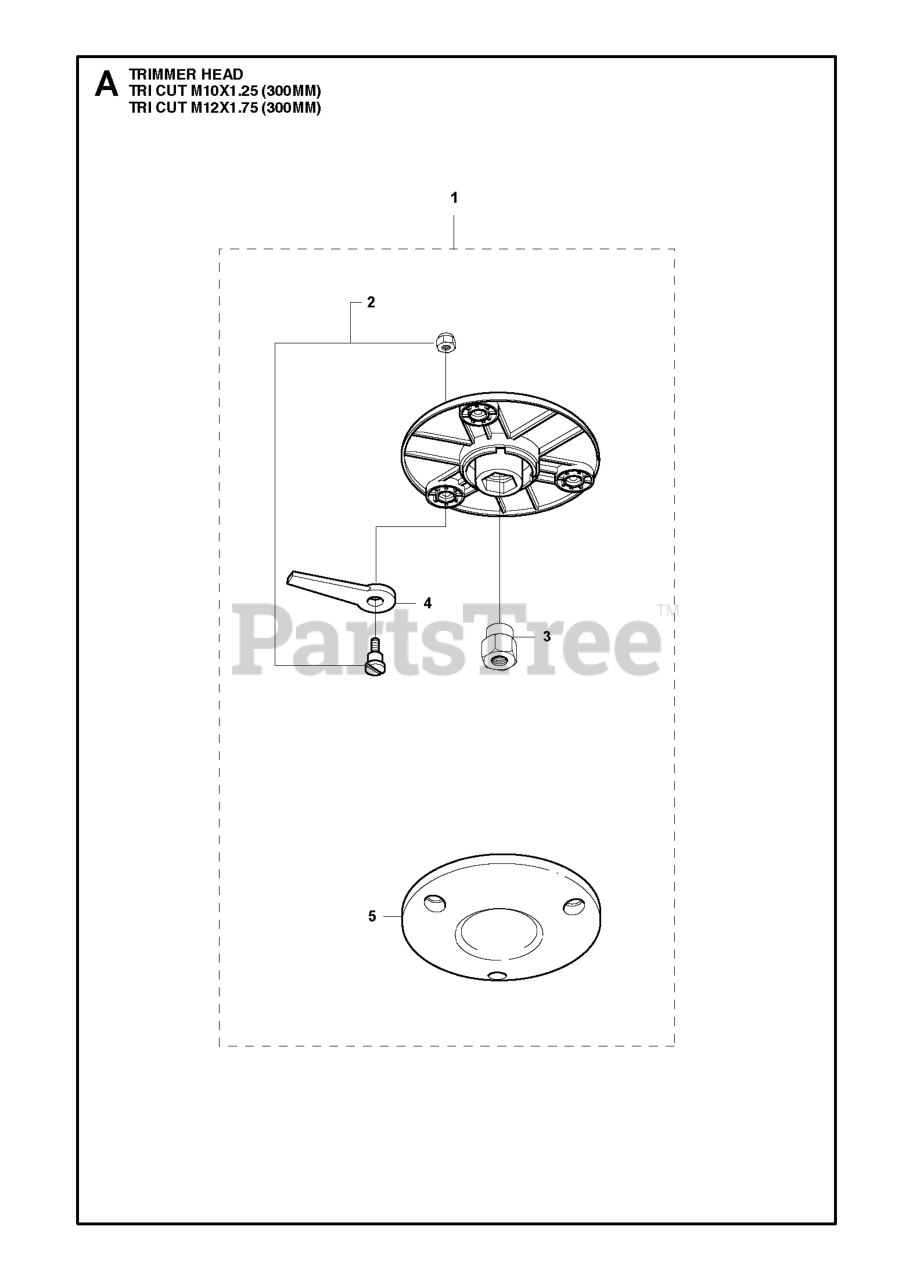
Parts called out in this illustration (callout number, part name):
2	SCREW/NUT/WASHER KIT
3	ADAPTOR M12 X 1.75
3	ADAPTOR M10 X 1.25
4	Blade/Tri Cut-Premium
5	LOWER HOUSING/TRI-CUT
